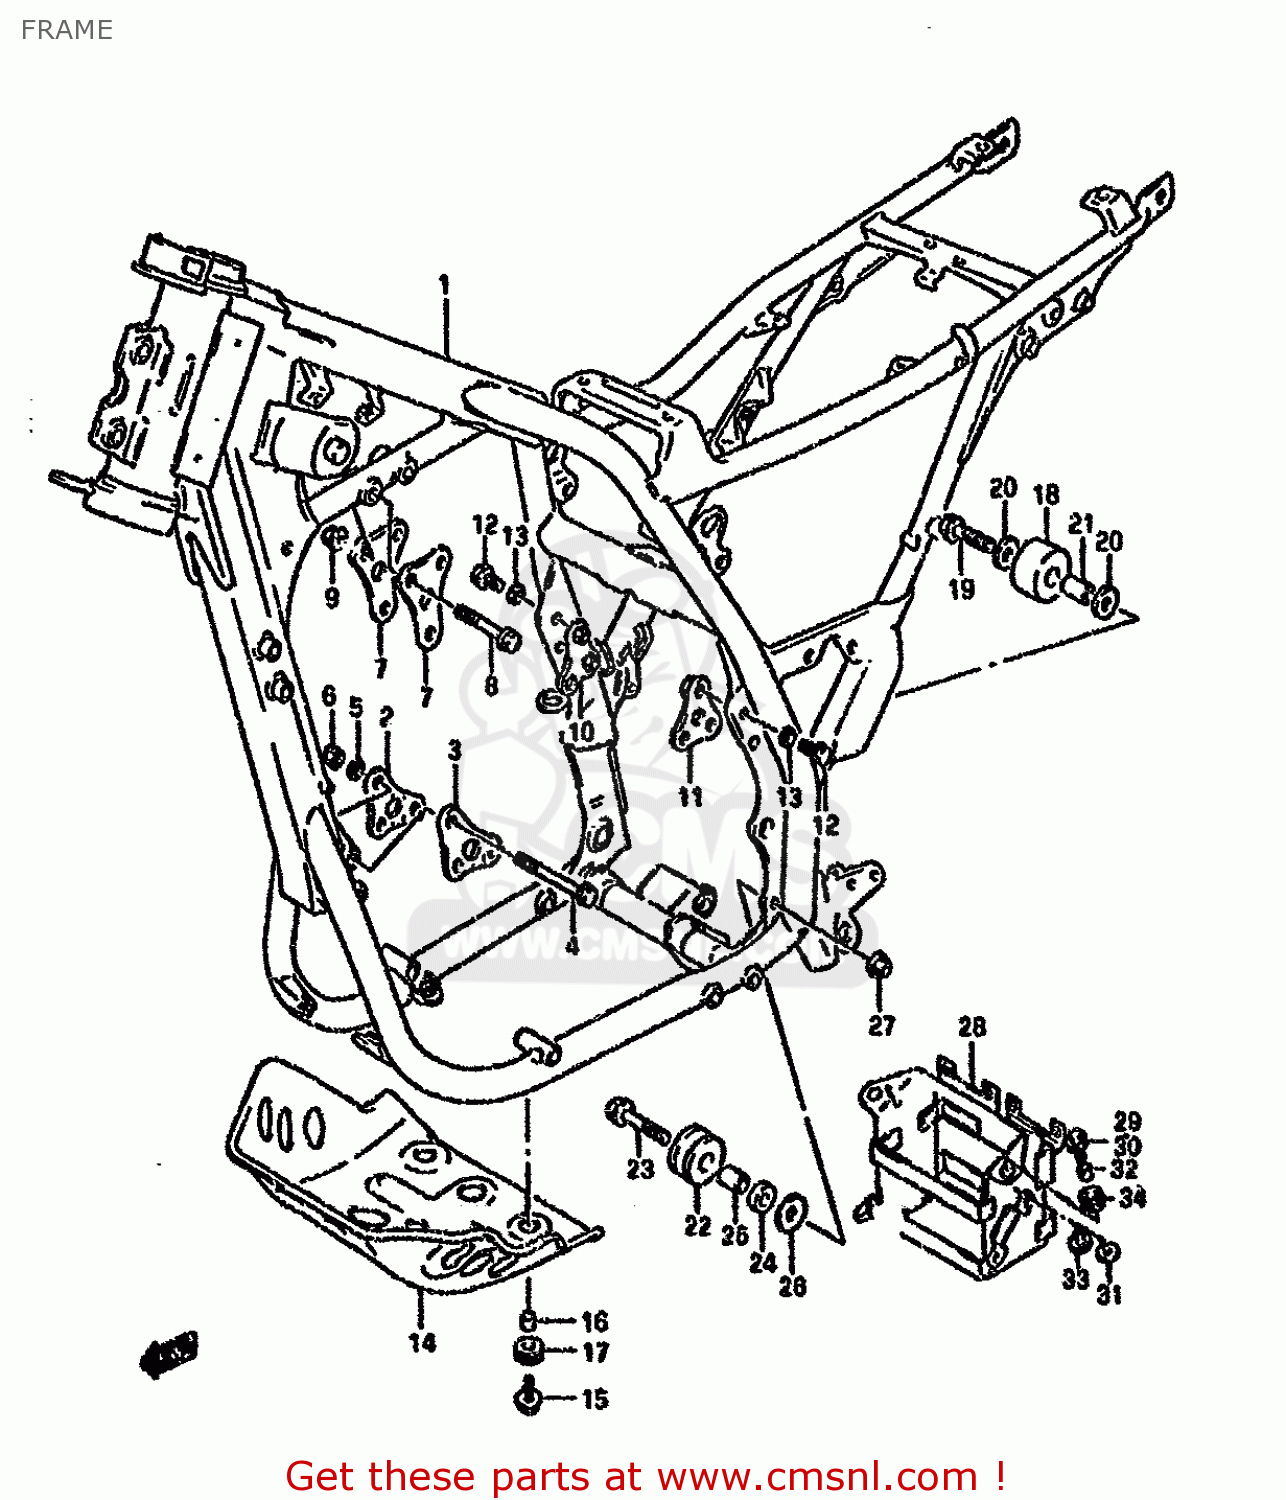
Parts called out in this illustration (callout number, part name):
1	FRAME (BLUE)
2	PLATE,ENG MTG FR,R
3	PLATE,ENG MTG FR,L
4	BOLT(8X72)
5	LOCK WASHER
6	NUT
7	PLATE,ENGINE MOUNTING
8	BOLT(8X50)
9	NUT
10	PLATE,ENG MTG RR,R
11	PLATE,ENG MTG RR,L
12	BOLT(8X20)
13	LOCK WASHER
14	PROTECTOR,ENGINE
15	BOLT 6X20
16	SPACER (7X9X7)
17	CUSHION
18	ROLLER,CHAIN CONTROL
19	BOLT(8X41)
20	WASHER (8.2X24X1.6)
21	SPACER (8.6X13.8X28)
22	ROLLER,CHAIN CONTROL
23	BOLT 8X50
24	SPACER(8.5X15X8.5)
25	SPACER(8.6X12X25.5)
26	WASHER
27	NUT
28	HOLDER,BATTERY
29	BOLT
30	BOLT(6X25)
31	WASHER (6.5X20X1.2)
32	SPACER(6.1X9X7.5)
33	SPACER COMP,BATTERY
34	CUSHION
